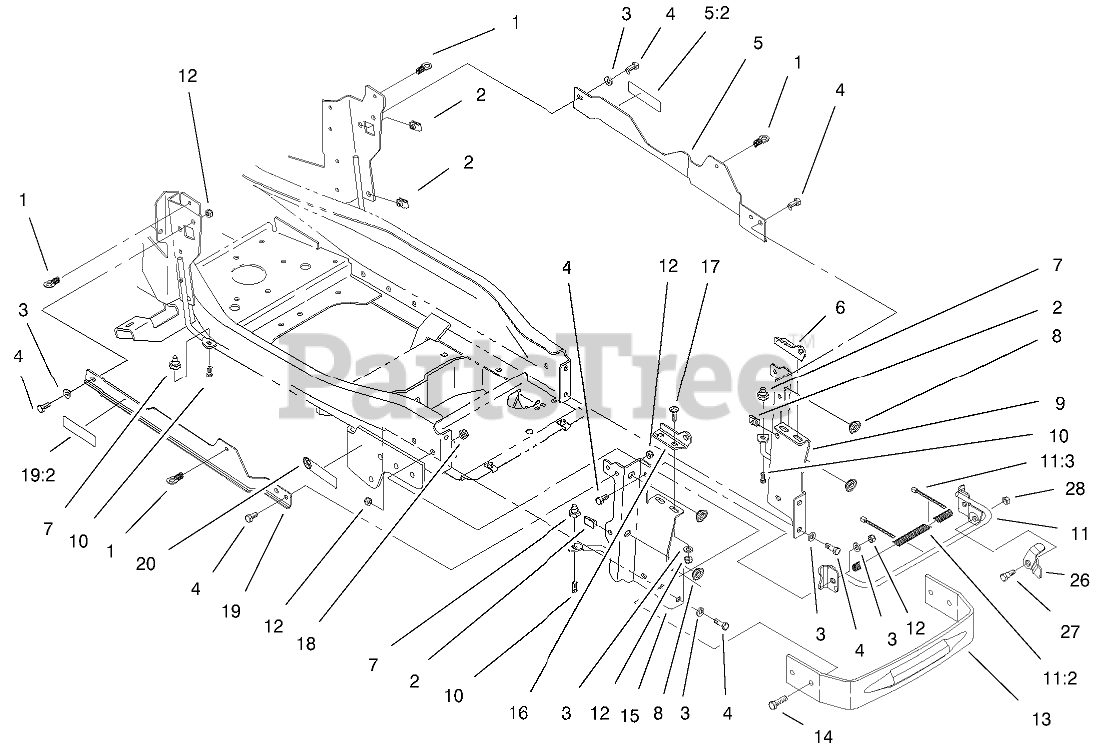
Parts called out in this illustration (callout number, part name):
1	LATCH ASM
3	WASHER-PLAIN
4	SCREW-HH
5	SUPPORT / DECAL ASM
5:2	DECAL-WARNING
6	BRACKET-HINGE, LOWER LH
7	MOUNT-SIDEPANEL
8	GROMMET
9	SUPPORT-HOOD, LH
10	SCREW-PLASTITE
11	SUPPORT-HOOD
11:2	COVER-BRACE
11:3	TIE-CABLE
12	NUT-LOCK, NI
13	BUMPER-FRAME
14	SCREW-HH
15	SUPPORT-HOOD, RH
16	BRACKET-HINGE, LOWER RH
17	SCREW-CARR
18	NUT-LOCK, NI
19	SUPPORT ASM
19:2	DECAL-WARNING
20	DECAL-ATTACH A-MATIC
26	LEVER-PROP, HOOD
27	BOLT-SHOULDER
28	NUT-LOCK, NI
